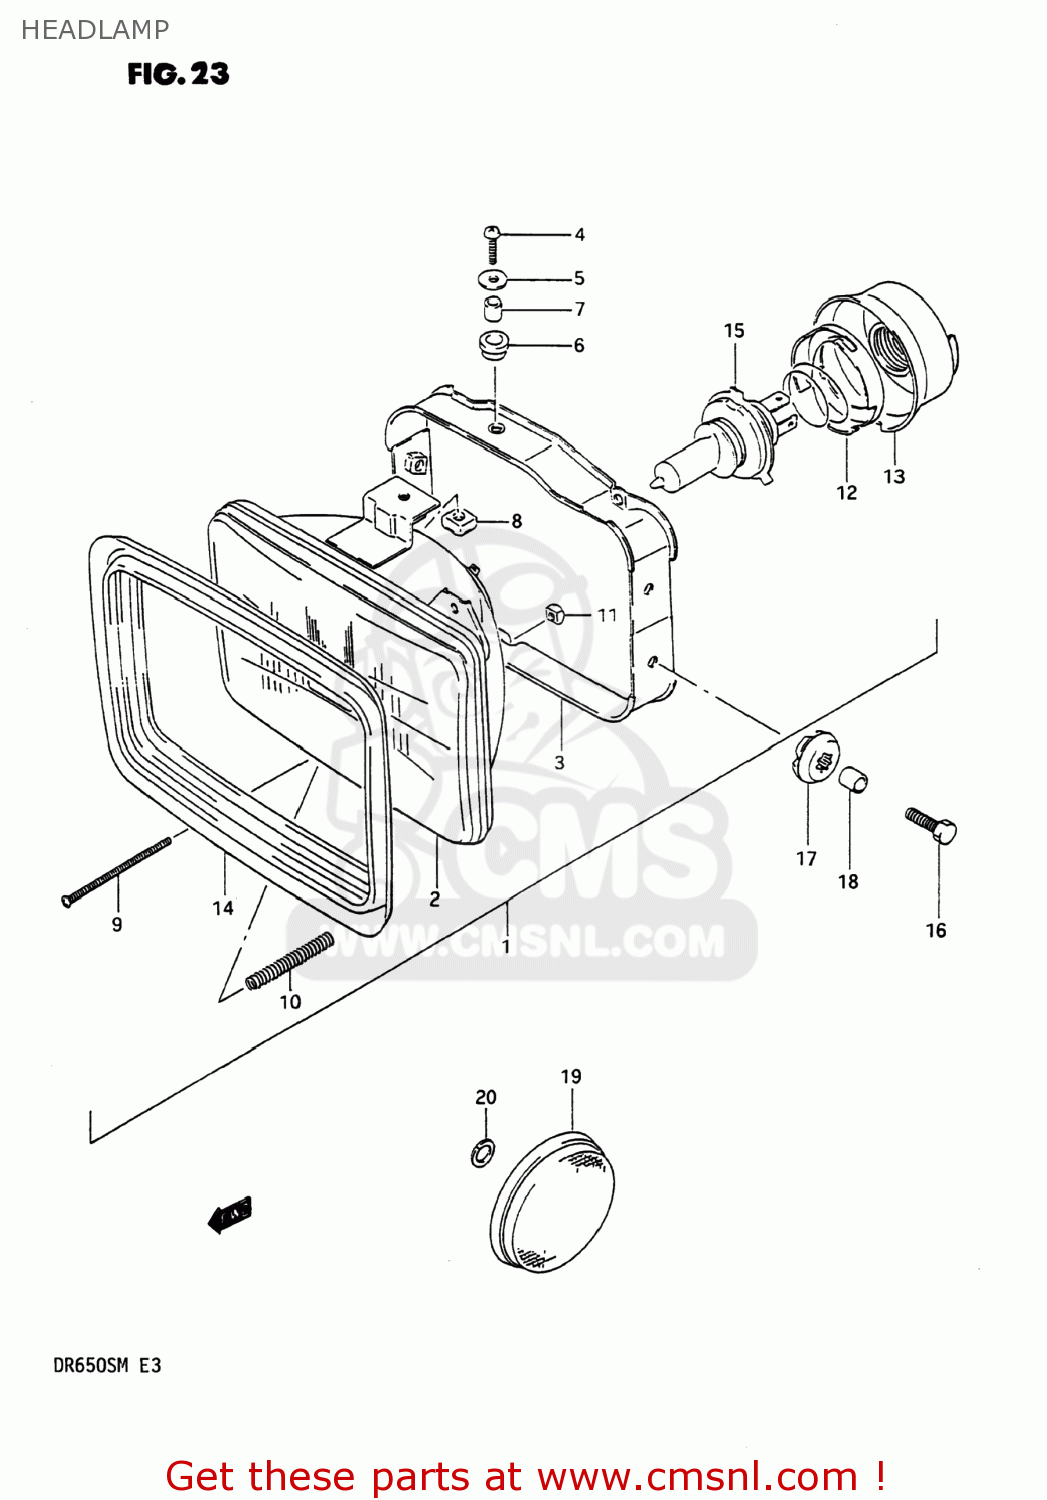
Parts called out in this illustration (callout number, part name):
1	HEADLAMP ASSEMBLY
2	LAMP UNIT
3	HOUSING
4	SCREW 5X20
5	WASHER
6	CUSHION
7	SPACER
8	NUT
9	SCREW,HEADLAMP ADJUST
10	SPRING
11	NUT
12	HOLDER,BULB
13	COVER,SOCKET
14	SHADE
15	BULB(12V60/55W,H4)
16	BOLT 6X20
17	CUSHION
18	SPACER (6.1X9X10)
19	REFLEX REFLECTOR,FR
20	LOCK WASHER
